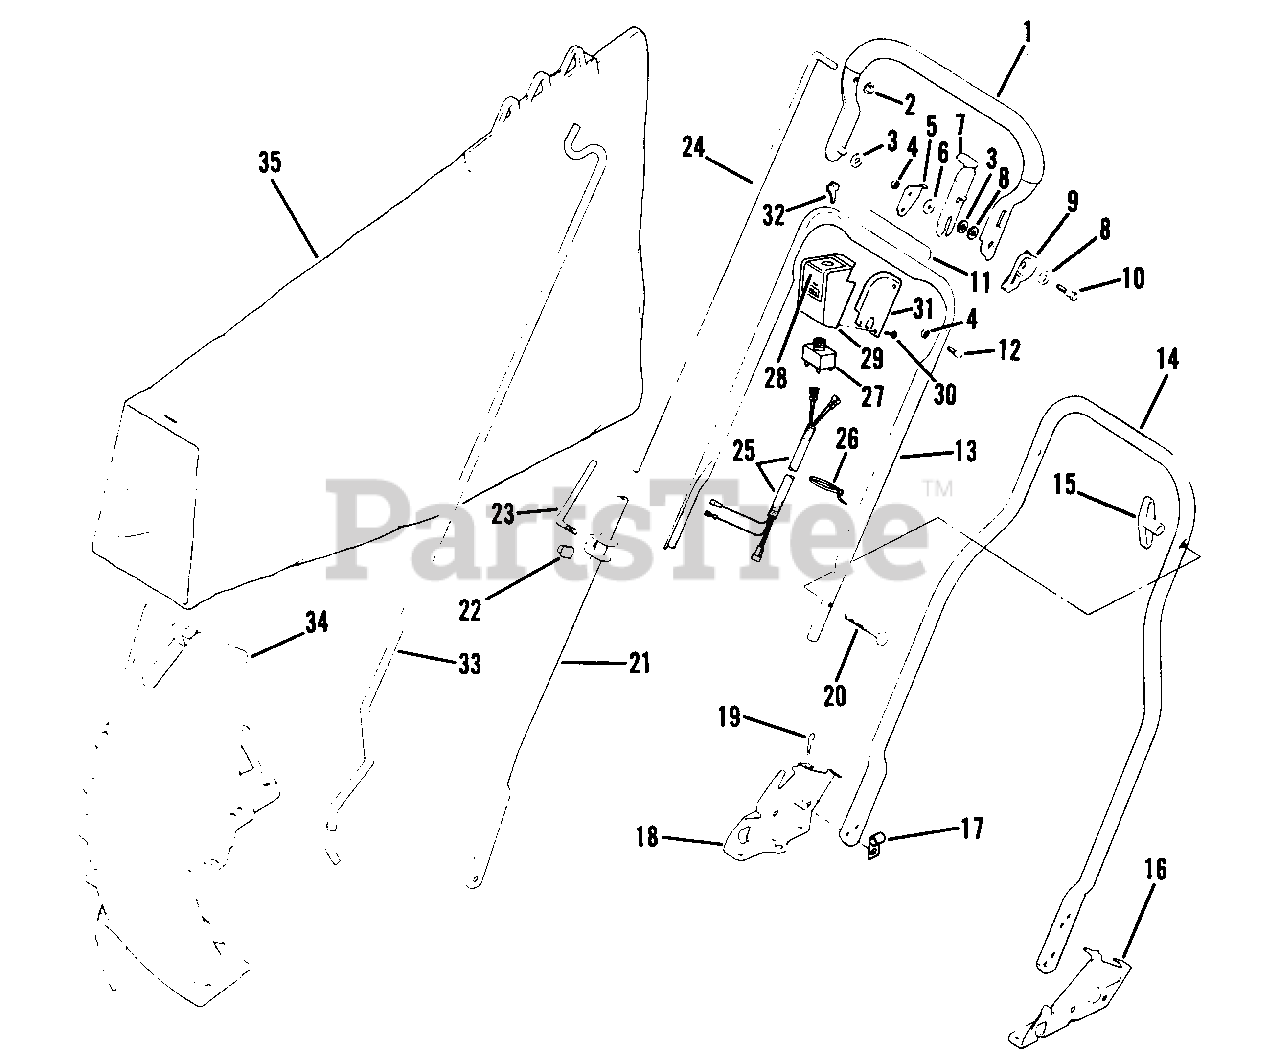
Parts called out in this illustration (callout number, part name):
1	Handle & Grip Assembly
2	Palnut
3	Washer
4	Nut-Lock
5	Stop-Handle
6	Washer
7	Lever-Lockout
8	Washer
9	Guard-Lever
10	Bolt-Shoulder
11	Decal
12	Screw-Stop
13	Handle-Center
14	Handle Section-Bottom
15	Knob
16	Bracket-Handle L.H.
17	Clamp
18	Bracket-Handle R.H.
19	Hair Pin
20	Screw
21	Control Lever Assembly
22	Nut
23	Screw
24	Control Rod
25	Wire Harness Assembly Switch
26	Cable Tie
27	Key Switch
28	Decal-Switch
29	Housing-Switch
30	Screw
31	Retaining Plate-Switch Housing
32	Keys-Switch
33	Rod-Grass Bag
34	Chute Assembly
35	Bag Assembly
